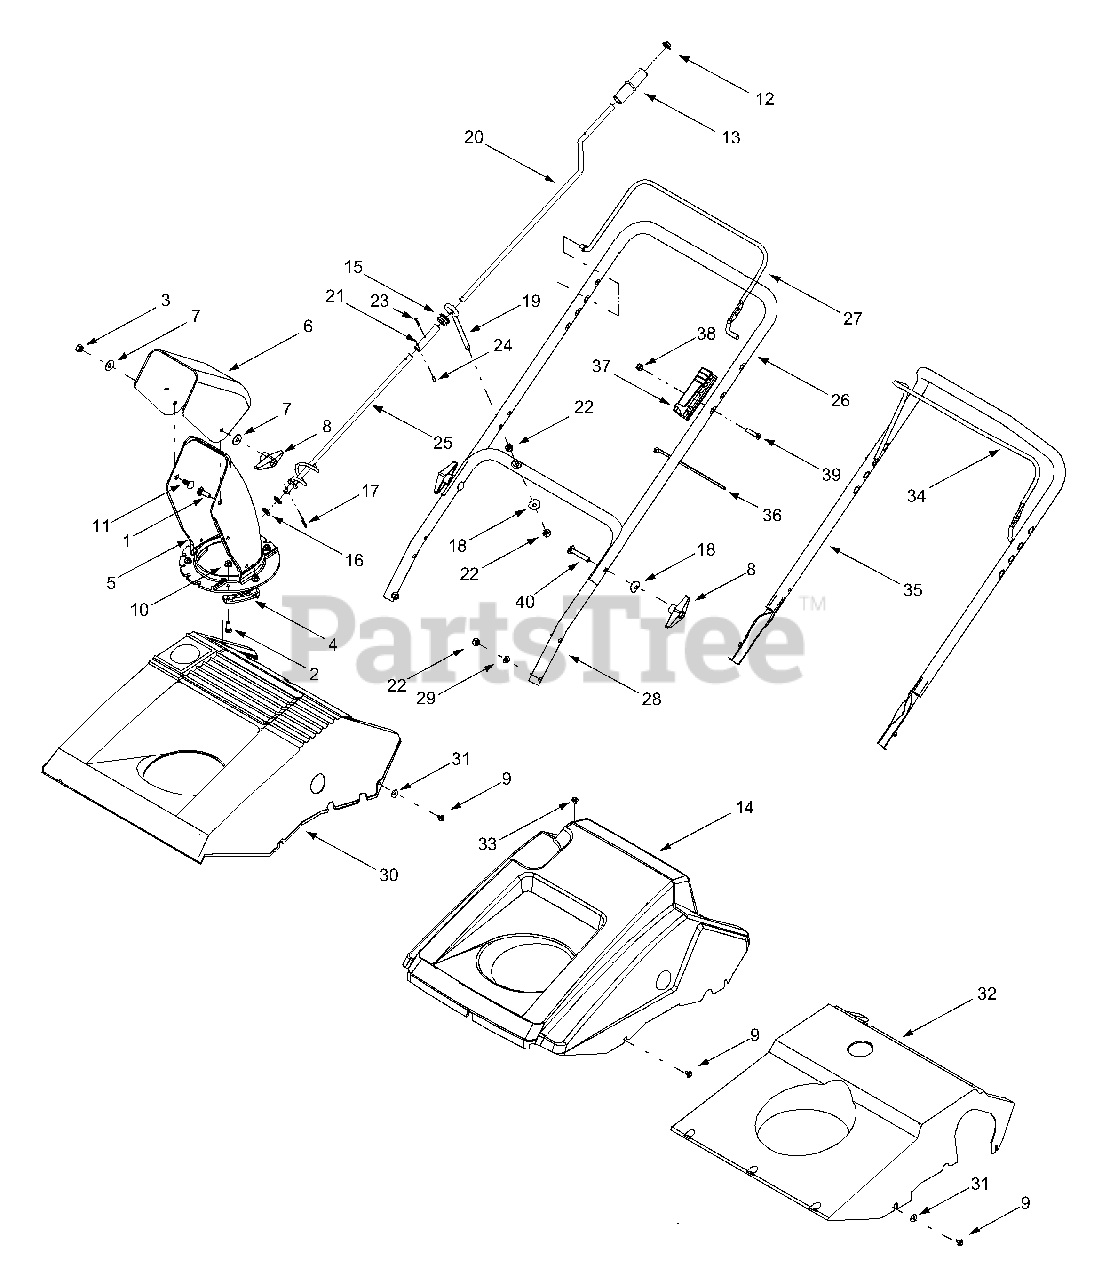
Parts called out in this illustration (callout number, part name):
1	Splined Carriage Screw, 5/16-18 x 1.0
2	Hex Cap Screw, 1/4-20 x.75
3	Hex Lock Nut, 5/16-18
4	Chute Flange Keeper
5	Lower Chute, 5.0
6	Upper Chute, 5.0
7	Washer, .349 x .879 x .063
8	Wingnut Knob, 5/16-18
9	Screw, #10-16 x .375
10	Hex Flange Lock Nut, 1/4-20
11	Carriage Bolt, 5/16-18 x .75
12	Push Cap, 3/8
13	Knob, 1.0 x 3.2
14	Shroud, Black-Models E162 & E172
15	Rubber Grommet, .44 x .94 x .50
16	Flat Washer, .375 x .738 x .063
17	Internal Cotter Pin, .072 x 1.12
18	Saddle Washer, .320 x .93
19	Eyebolt, .70
21	Spacer, .382 x .50 x 1.12
22	Hex Nut, 5/16-18
23	Cotter Pin, 3/32 x .75
24	Rolled Pin, 1/8 x .63
30	Shroud, Black-Models 150 & E150
31	Flat Washer, .194 x .62 x .063
32	Shroud, Black-Model 140
33	Screw, #10-16 x .625
36	Cable Tie
37	Control (Cable) Housing
38	Nylon Hex Lock Nut, 1/4-20
39	Machine Screw, 1/4-20 x 1.31
40	Carriage Screw 5/16-18
